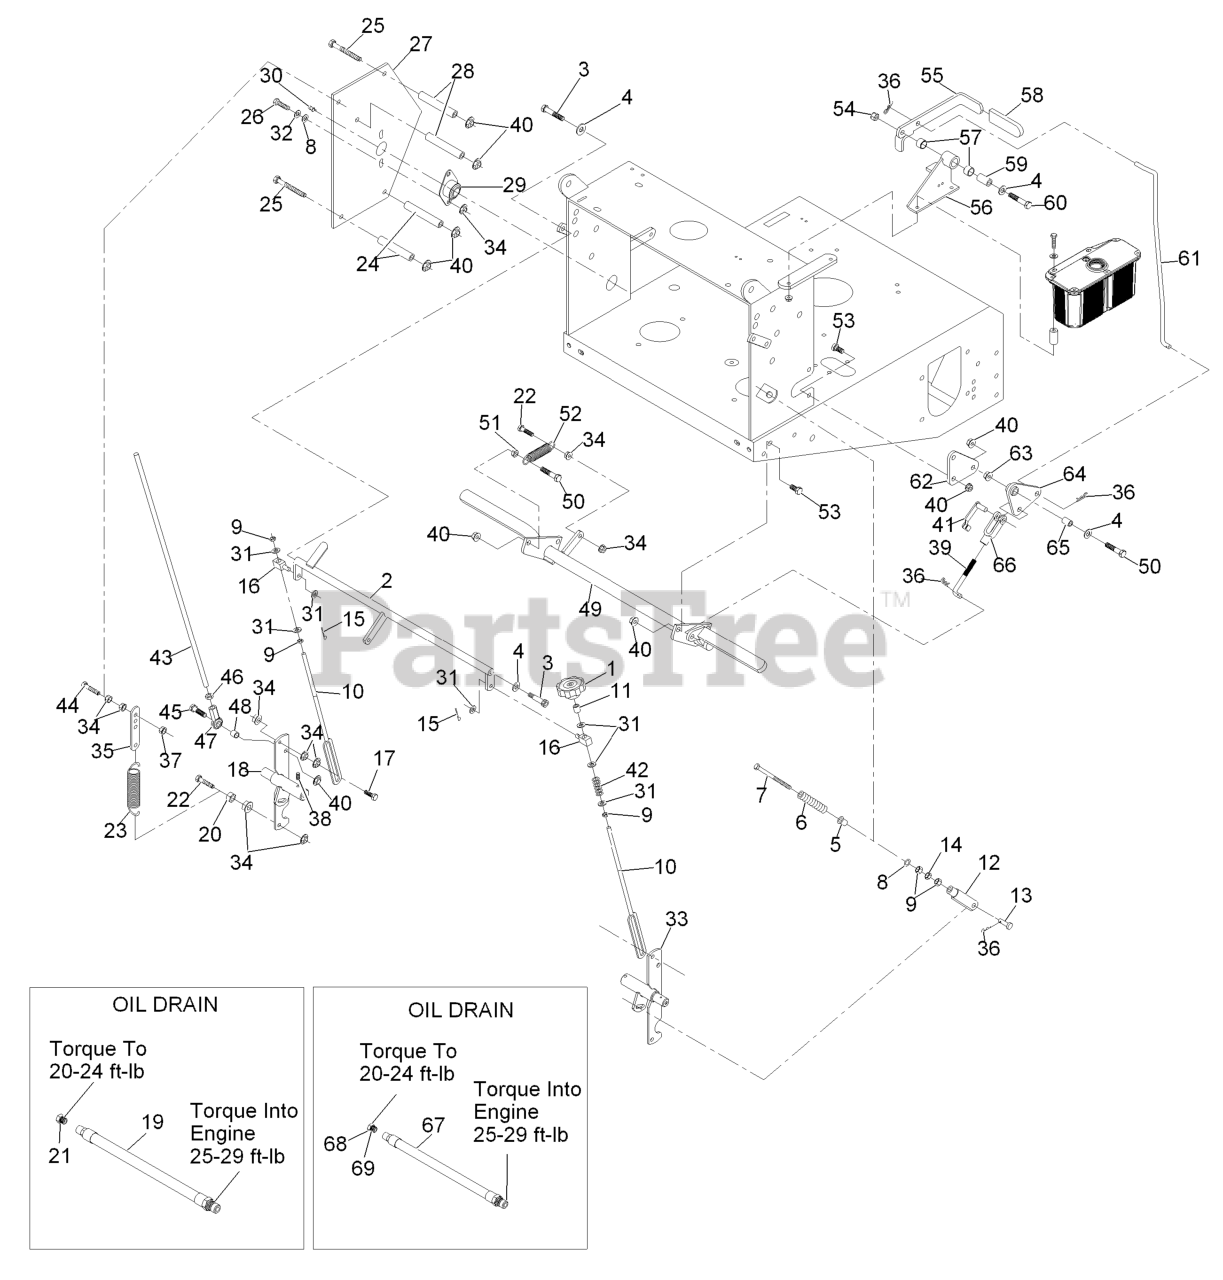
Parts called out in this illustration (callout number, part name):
1	KNOB-TRACKING
2	CRANK-CONTROL, SPEED
3	SCREW-HSH
4	WASHER-FLAT
5	BUSHING-FLANGED
6	SPRING,COMPRESSION (NEUT)
7	BOLT-RETURN, NEUTRAL
8	WASHER-FLAT
9	NUT-HEX
10	LINK-CONTROL, SPEED
12	YOKE-ADJUSTABLE
13	PIN-CLEVIS
14	NUT-JAM
15	PIN-COTTER
17	SCREW-HH
18	SHAFT-CONTROL, LH
20	NUT-JAM
22	SCREW-HH, SPECIAL
23	SPRING-EXTENSION
24	SPACER-SHIELD
25	SCREW-HH
26	SCREW-HH
27	SHIELD-CONTROL
28	SPACER-SHIELD
29	BEARING-FLANGE, SIDE
30	FITTING-GREASE
31	WASHER-PLAIN
32	WASHER-LOCK
33	SHAFT-CONTROL, RH
35	TAB-SPRING, EXTENSION
36	PIN-COTTER
37	NUT-LOCK, NI
38	SCREW-SET
39	LINKAGE-LOWER
40	NUT-HHF, WHIZ
41	PIN-SPRING, CLEVIS
42	SPRING-COMPRESSION
43	LINKAGE,DRIVE (PLT)
44	BOLT-TAP, HH
45	SCREW-HH
46	NUT-HEX JAM, LH
47	JOINT-BALL END, LH
48	SPACER-TUBE, PUMP LINK
50	SCREW-HH
51	NUT-JAM
52	SPRING-IDLER
53	SCREW-HH
54	NUT-LOCK, NI
55	LEVER,PARK BRK W/DECAL
56	BRACKET ASM
57	SLEEVE-BUSHING
58	GRIP-LEVER
59	BUSHING-PIVOT
60	SCREW-HH
61	LINKAGE-UPPER
62	BELLCRANK
64	BELLCRANK ASM
65	BUSHING-PLASTIC
66	YOKE-LINKAGE, BRAKE
67	ASM, ENGINE OIL DRAIN HOS
68	PLUG-HH
69	O-RING
